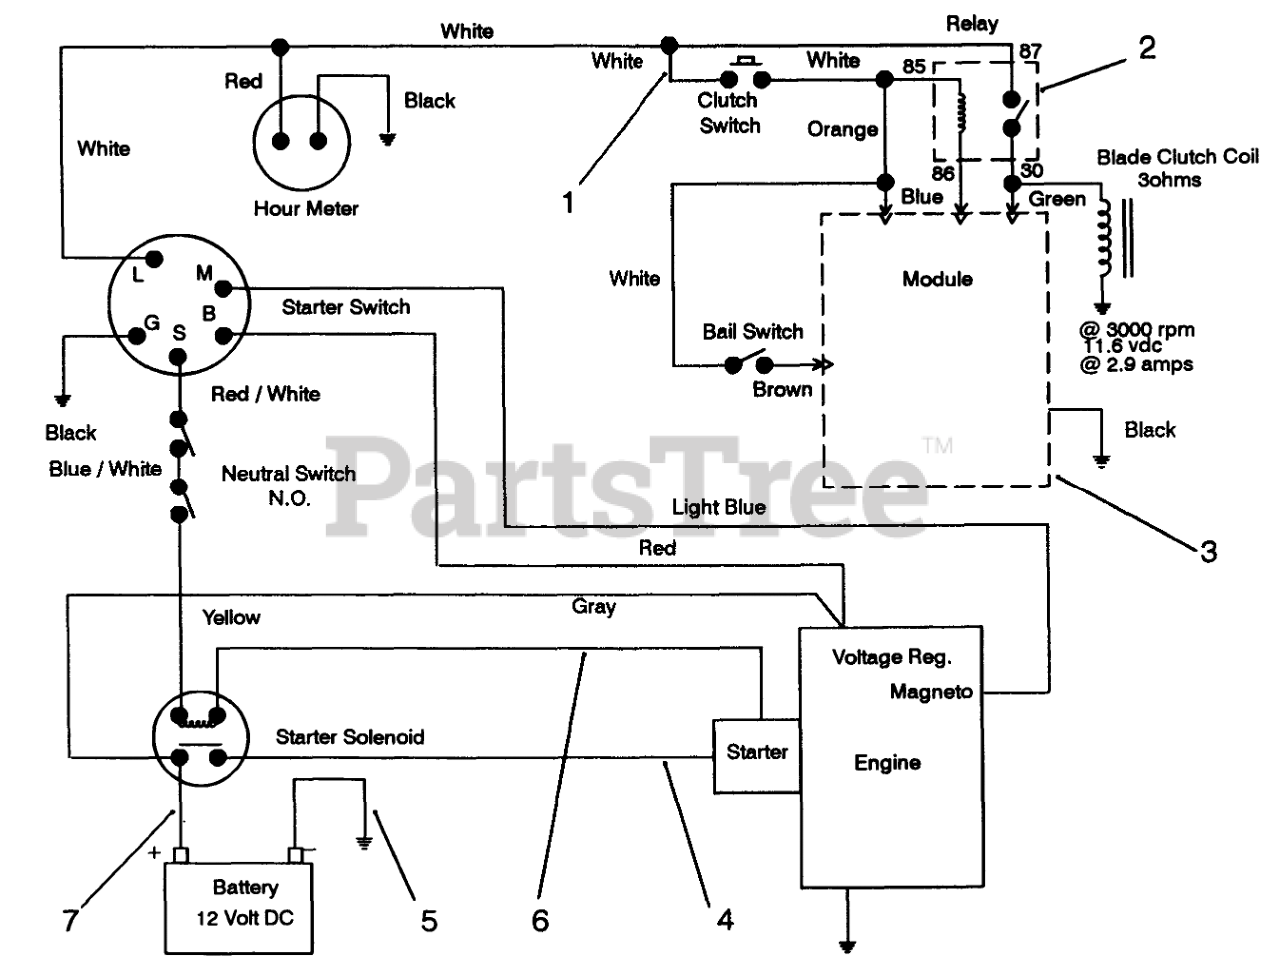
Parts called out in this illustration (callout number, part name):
1	WIRE HARNESS
2	RELAY
3	Module
4	WIRE-SOLENOID/STARTER
5	CABLE-BATTERY, NEGATIVE
6	WIRE ASM
7	WIRE ASM
